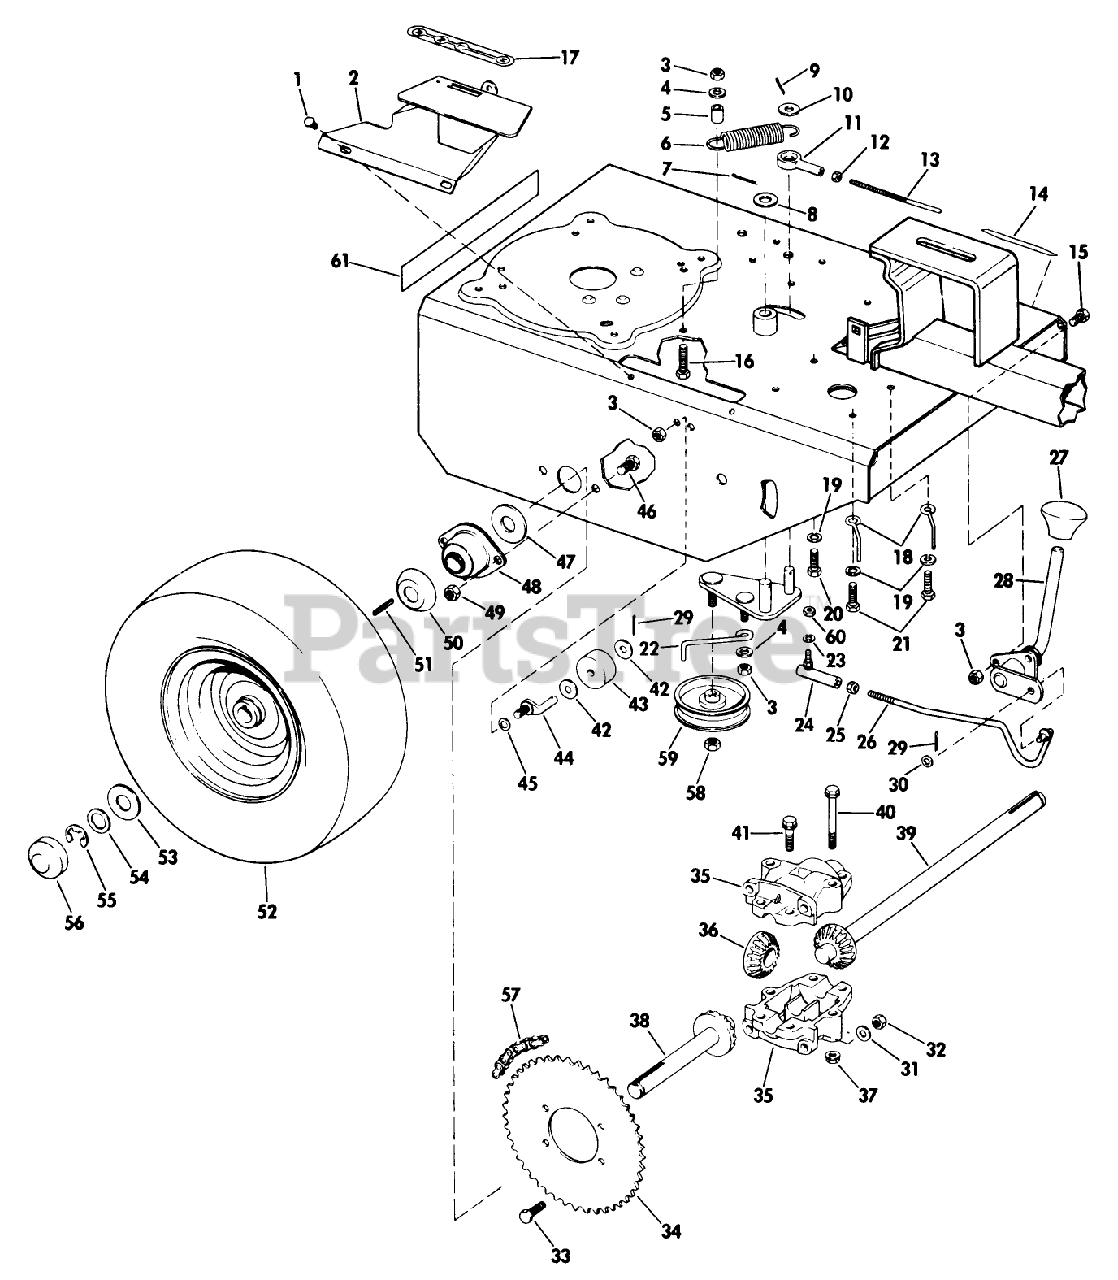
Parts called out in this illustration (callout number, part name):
7	Cotter Pin
25	Jam Nut
45	Lockwasher
49	LOCKNUT
60	Plug-Core
